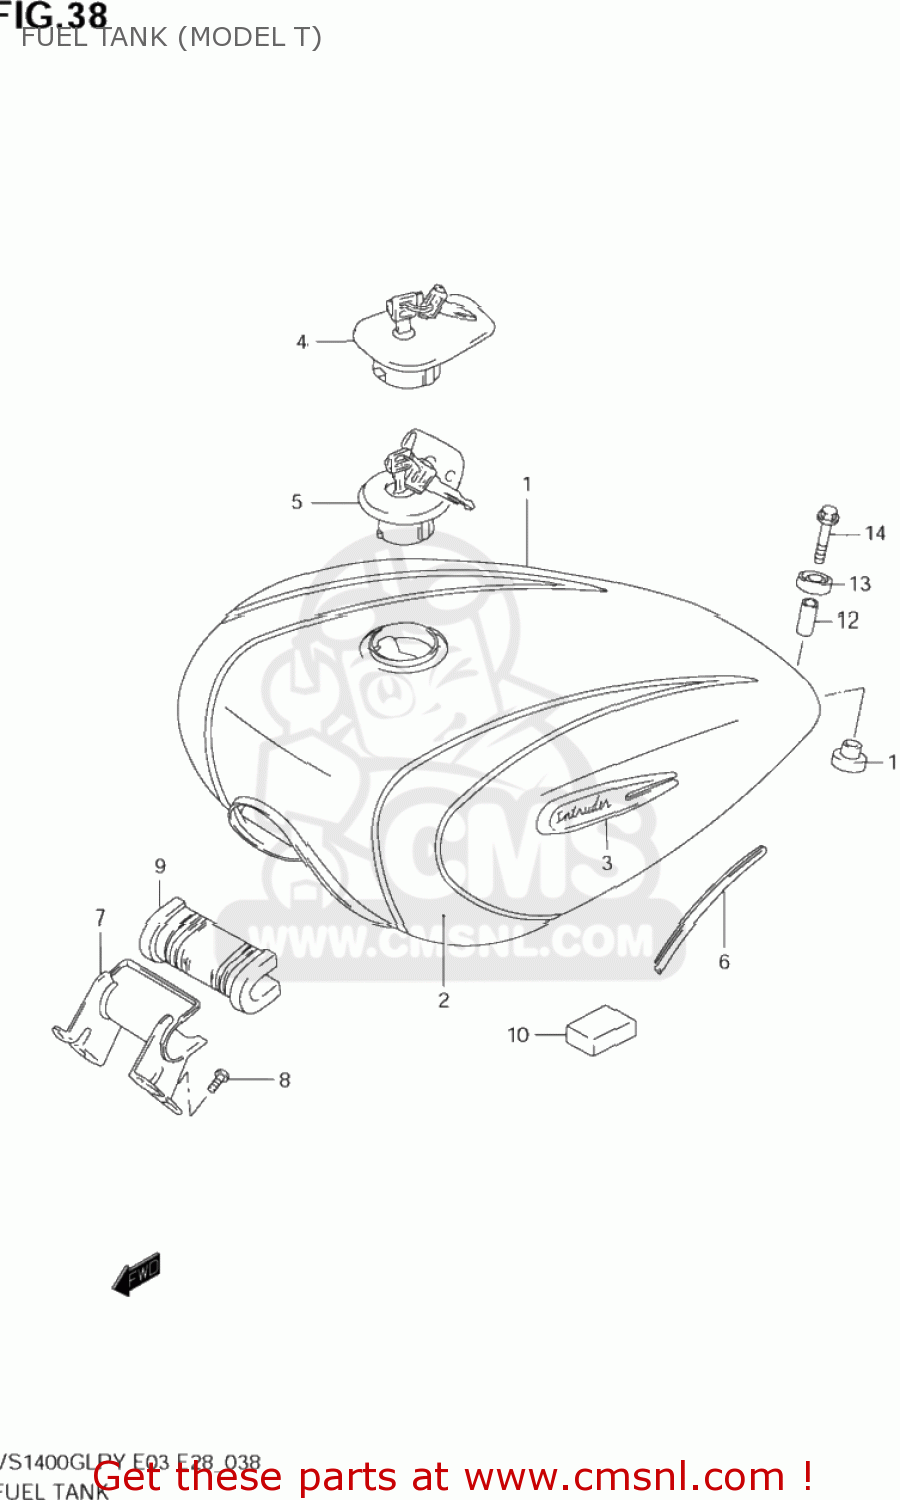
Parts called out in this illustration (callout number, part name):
1	TANK ASSEMBLY,FUEL
2	TAPE SET,FUEL TANK STRIPE
3	EMBLEM,FUEL TANK,R
4	CAP SET,FUEL TANK
5	CAP SET,FUEL TANK
6	MOLDING,FUEL TANK
7	BRACKET,TANK
8	SCREW
9	CUSHION,FUEL TANK FR
10	CUSHION
11	CUSHION
12	SPACER
13	CUSHION
14	BOLT
